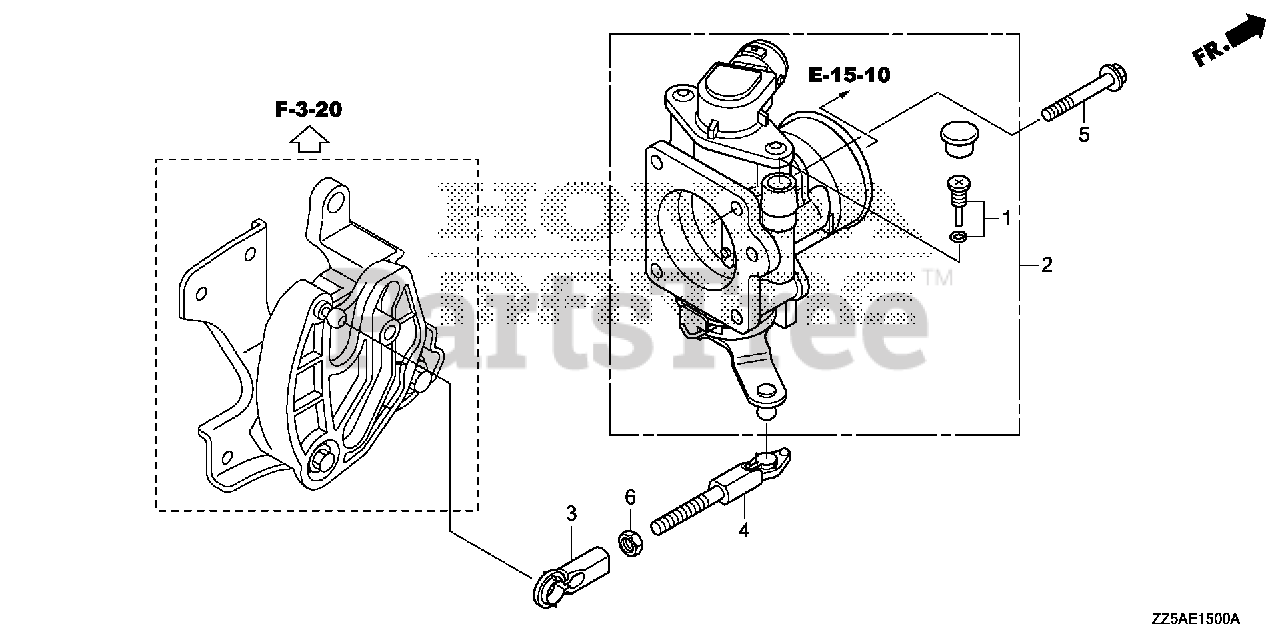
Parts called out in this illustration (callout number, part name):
2	BODY ASSY., THROTTLE
3	LINKAGE, PIVOT
4	ROD, THROTTLE
5	BOLT, FLANGE (6X50)
6	NUT, HEX. (5MM)
